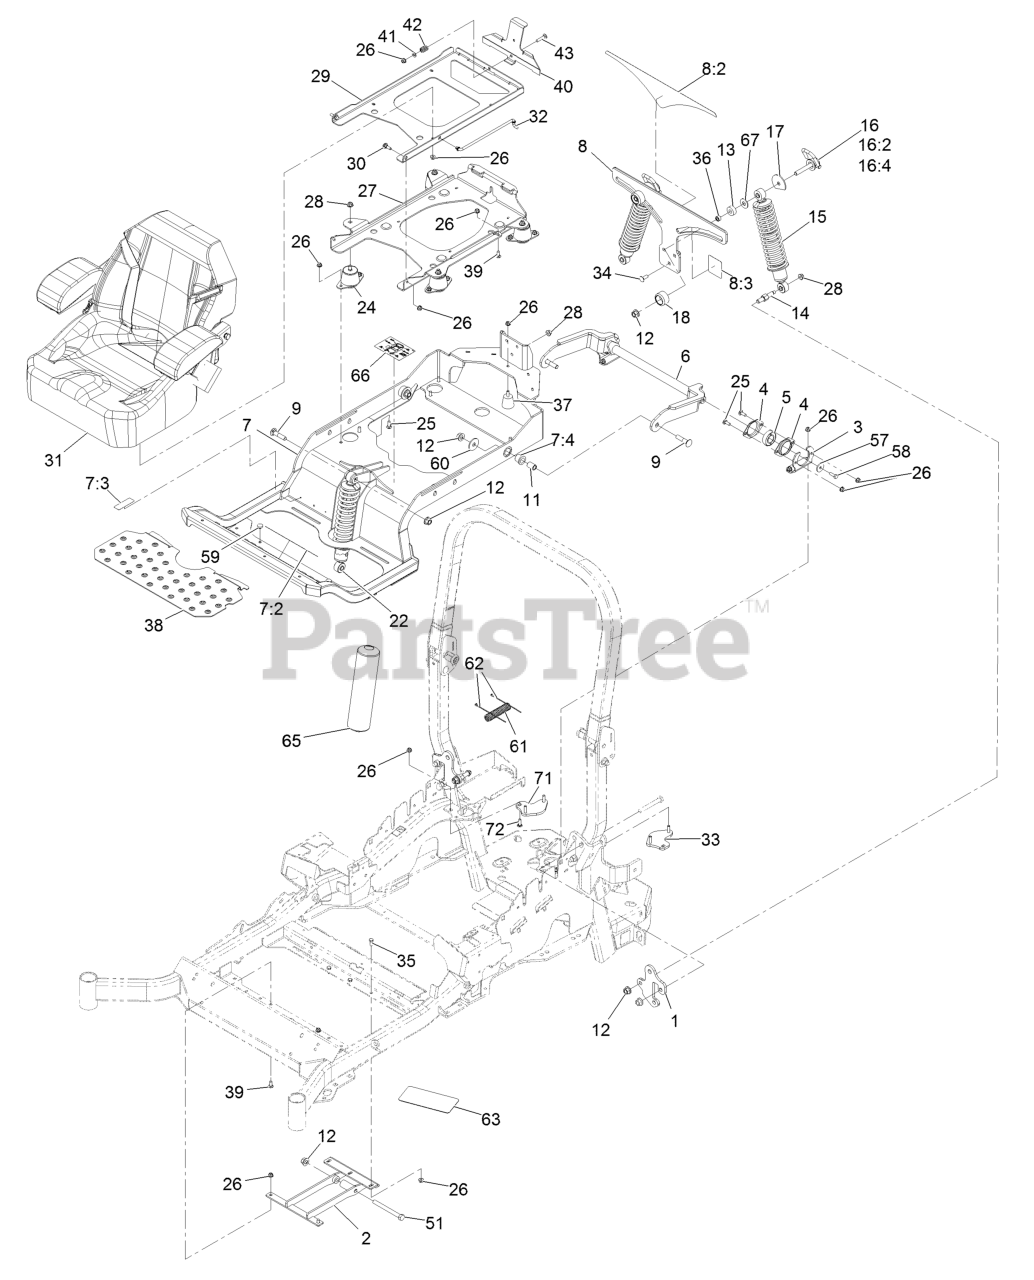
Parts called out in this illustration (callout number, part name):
1	PLATE-MOUNT, SHOCK
2	MOUNT-LOWER
3	BRACKET-BEARING
4	HOUSING-BEARING, FLANGE
5	BEARING
6	ARM-TRAILING
7	SUBFRAME ASM
7:2	DECAL-DANGER
7:3	DECAL-BRAKE, PARKING
7:4	BUSHING-FLANGE
8	BRACKET-MOUNTING
8:2	DECAL-ADJUSTMENT, RIDE
8:3	DECAL-LOCK, CAM
9	SCREW-CARR
11	SPACER-ALUMINUM
12	Nut-Lock 1/2-13
14	BOLT-SHOULDER
15	SHOCK/SPRING ASM
16	CAM LOCK ASM
16:2	CAP-LOCK
16:4	NUT-HEX
17	PLATE-STOP
18	KNOB-FRONT
24	ISOLATOR-SEAT
25	BOLT-CARR
26	NUT-HF, NI
27	PLATE-SUPPORT, ISO SEAT
28	NUT-HF, NI
29	PLATE-FRAME, SEAT
30	SCREW-SHOULDER
31	SEAT-EXMARK STANDARD
32	ROD-PROP
33	LH PLATE ASM (W/STUDS)
34	SCREW-CARR
35	SCREW-HH
36	BEARING-NEEDLE
37	BUMPER-RUBBER
39	SCREW-CARR
40	PLATE-LATCH,SEAT
41	WASHER-PLAIN
42	SPRING-COMPRESSION
43	BOLT-CARR
51	SCREW-HH
57	WASHER-FLAT
58	SCREW-HH, THREAD LOCKING
60	WASHER-THRUST
61	COVER-HOSE
62	TIE-CABLE
63	TREAD-GRIP
65	COVER-SHOCK
66	DECAL-SERVICE AID
67	WASHER-FLAT
71	RH PLATE ASM (W/STUDS)
72	SCREW-CARR
